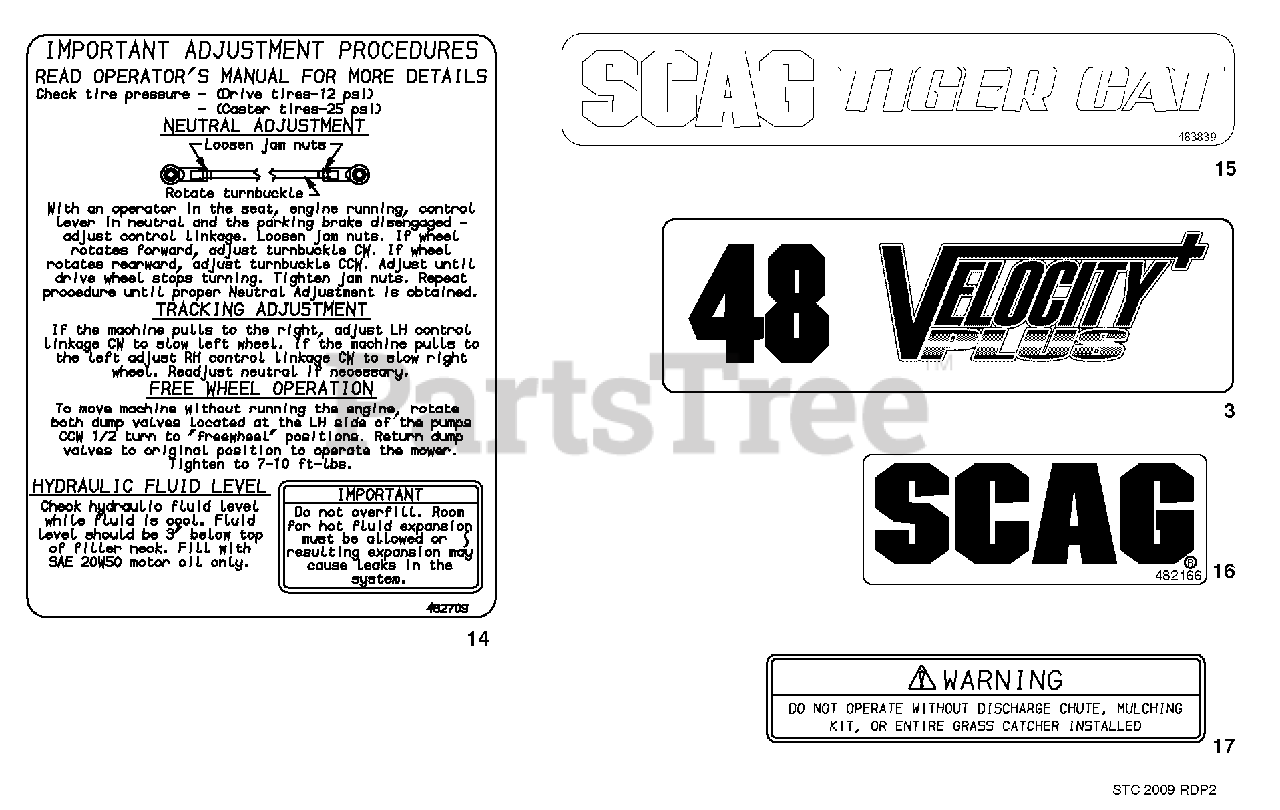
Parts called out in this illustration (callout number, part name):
3	Decal
14	Decal, Seat Support
15	Decal, Rear Bumper
16	Decal, Front Footplate
17	Decal, Discharge Chute
